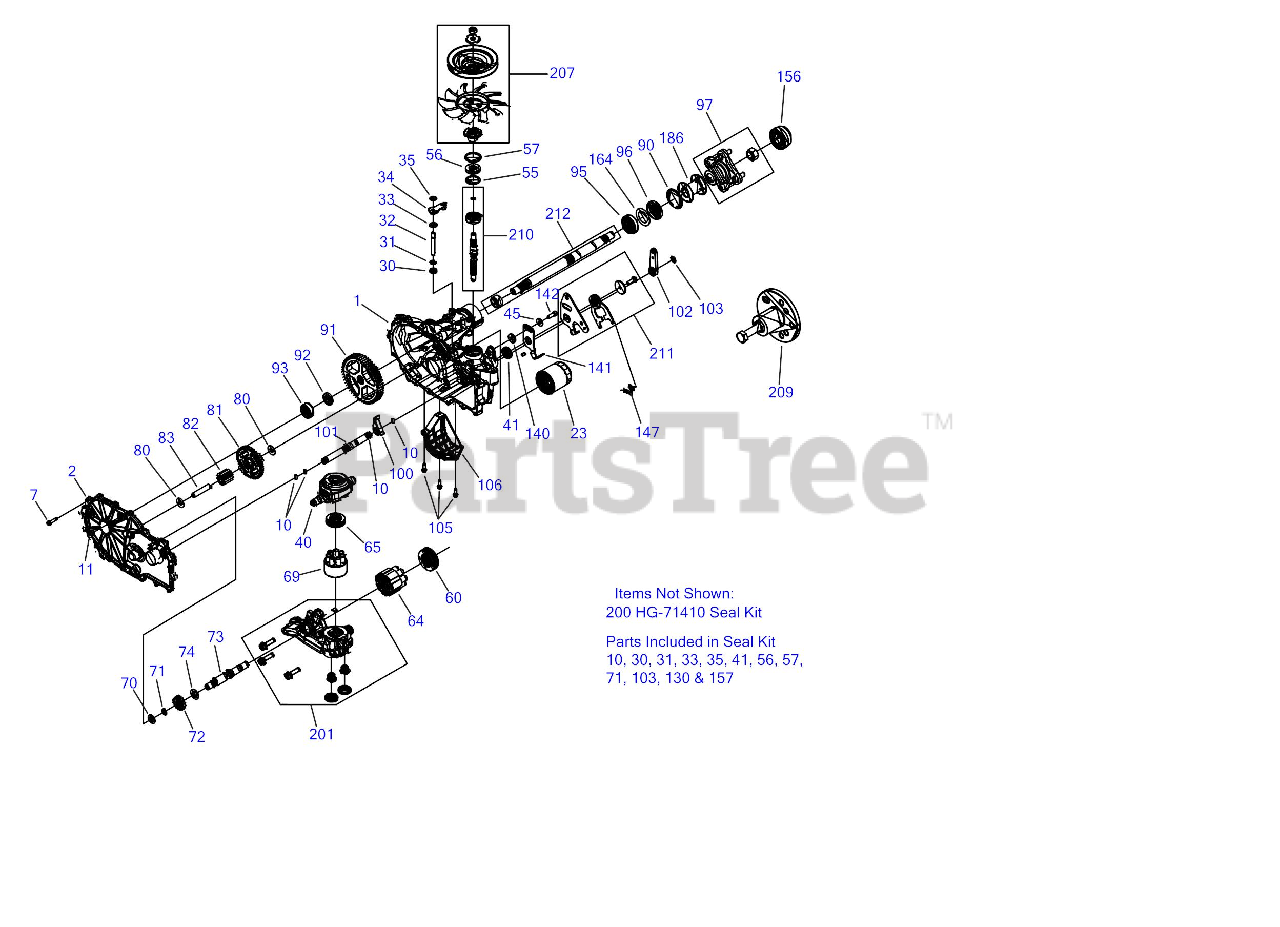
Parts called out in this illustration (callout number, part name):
1	Kit, Main Housing, LH Control
2	Kit, Side Cover, LH
7	Screw, Hex Washer
23	Filter, Spin-On 2.6 x 3.0
30	Seal, Lip, .375 x .75 x .25
31	Ring, Retaining .375 External
32	Rod, Bypass
33	Ring Retaining .750 Internal
34	Arm, Bypass
35	Ring, Ret .375 External
40	Trunnion, Swashplate
41	Seal, Lip 18 x 32 x 7
45	Washer, .34 x .88 x .06
55	Washer, 1.23 x 1.57 x .04
56	Seal, Lip 17 x 40 x 7
57	Ring Retaining Internal
60	Bearing, Thrust 35 x 62 x 18
64	Kit, 16cc Cylinder Block Assembly
65	Thrust Bearing, 30 x 52 x 13
69	Kit, Block, 7 Piston
70	Washer, .63 x 1.00 x .05
71	Ring, Reatining, Motor Shaft
72	Gear, 16T
73	Shaft, Motor
74	Washer, .71 x 1.16 x .04
81	Gear, 43T
82	Gear, 11T
83	Pin, Jackshaft
90	Ring, Retaining 2.25 Internal
91	Gear, 54T
92	Spacer, .750 x 1.00 x .257
93	Bearing, Ball 3/4 x 40mm x 12mm
95	Bearing, Ball 25.4 x 52 x 15
96	Seal, Lip, 1.0 x 2.06 x .38
97	Kit, Hub 4-Bolt
100	Pawl, Brake
101	Kit, Brake Shaft
102	Handle, Actuating
103	Ring, Retaining .438 External
105	Screw, Hex Washer 1/4-20 x .75
106	Guard, Filter, LH
140	Spacer, .320 x 1.005 x .150
141	Arm, Return Left
142	Socket Cap Screw, 5/16-24 x 7/8
147	Spring, Extension
156	Cap, Axle
164	Spacer, 1.355 x 2.035 x .021
186	Tube, Axle 2.03
200	Kit. Seal, ZT-2800
201	Kit, Center Section LH
207	Kit, Fan Pulley
207	Fan Only
207	Pulley Hub
209	Kit, Hub Puller
210	Kit, Input Shaft
211	Kit, RTN Bidirectional
212	Kit, Shaft Axle
